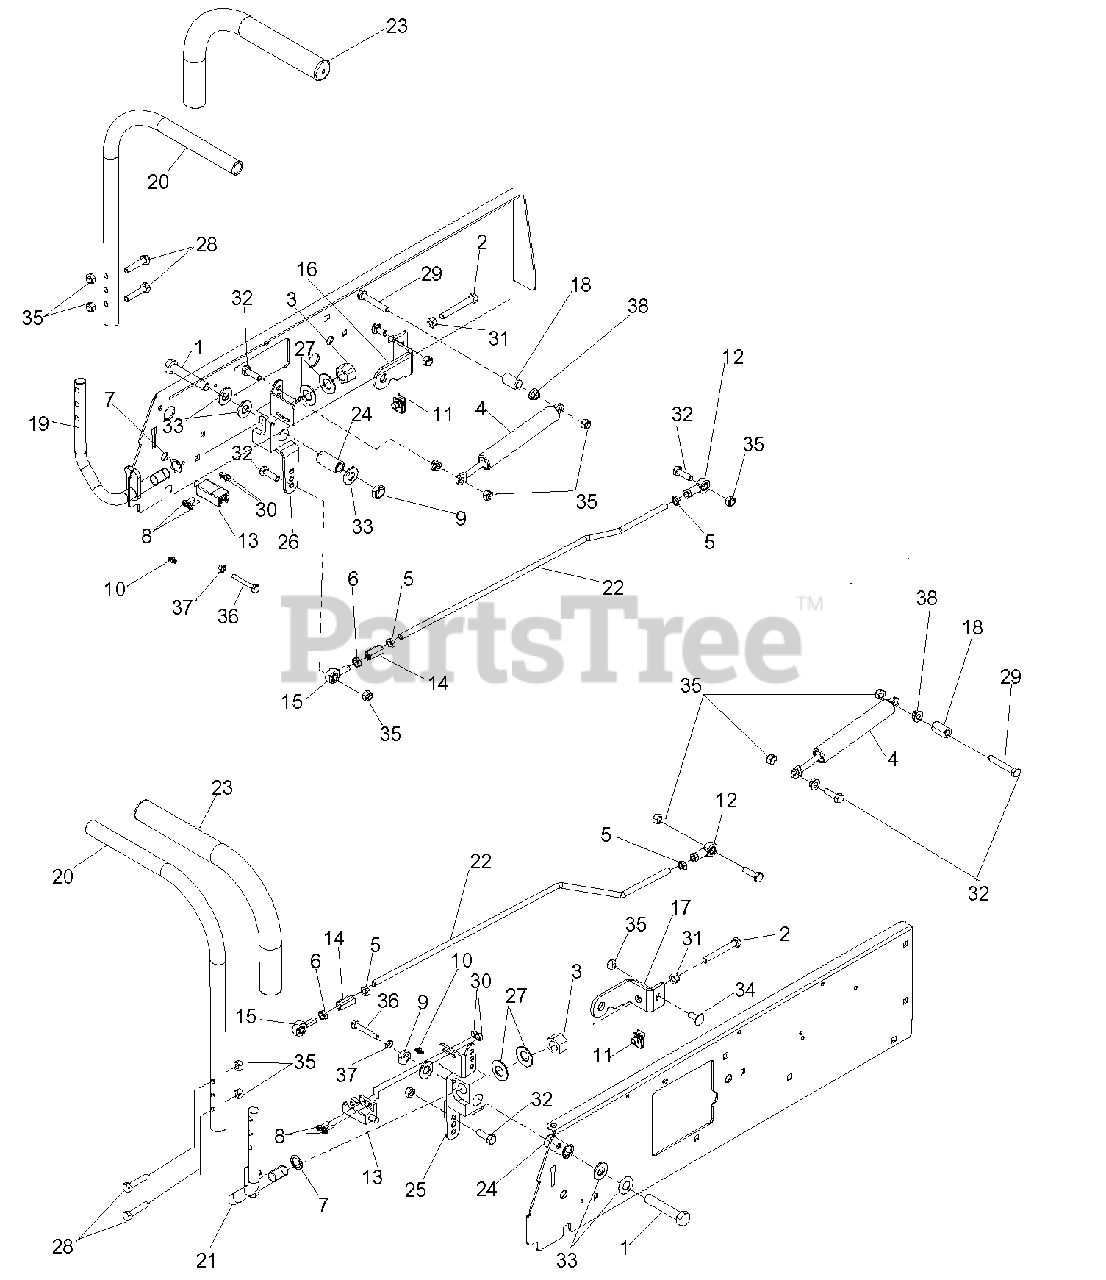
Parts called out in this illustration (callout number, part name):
1	HCS 1/2C X 2 3/4
2	HCS 5/16-18 X 2 1/2 TPBLT
3	NUT 5/8-11 NYLOC
4	DAMPENER, DUAL ACTION
5	NUT 5/16-24 UNF HEX JAM
6	5/16 24UNF NUT LH TH
7	WASHER-.626IDX.056TK
8	SCREW #10-24 X 5/8
9	NUT, 1/2-13 THIN PROF NYL
10	ZERK, 3/16, DRIVE IN
11	CLIP NUT 5/16-18
12	RH ROD END
13	SWITCH, INTERLOCK
14	ROD END COUPLER
15	ROD.END.LH
16	FORWARD STOP RH
17	FORWARD STOP LH
18	BUSHING
19	LEVER.PLATED.RH
20	LEVER UPPER
21	LEVER PLATED LH
22	CONTROL ROD
24	BUSHING
25	PIVOT LH (PLATED)
26	PIVOT RH (PLATED)
27	WASH 5/8 BEVELED DISC SPRING
28	CAPSCREW 5/16 X 1/1/2 HEX HEAD
29	HCS 5/16-18X2
30	NUT 10-24 NYLOC
31	NUT 5/16C HEX
32	HCS 5/16C X 1
33	WASHER 1/2" FLAT
34	BOLT 5/16C X 3/4" CARRIAGE
35	NUT 5/16 NYLOC
36	BOLT 1/4C X 1 3/4
37	NUT 1/4-20 JAM
38	5/16-18 FLANGED L-NUT
